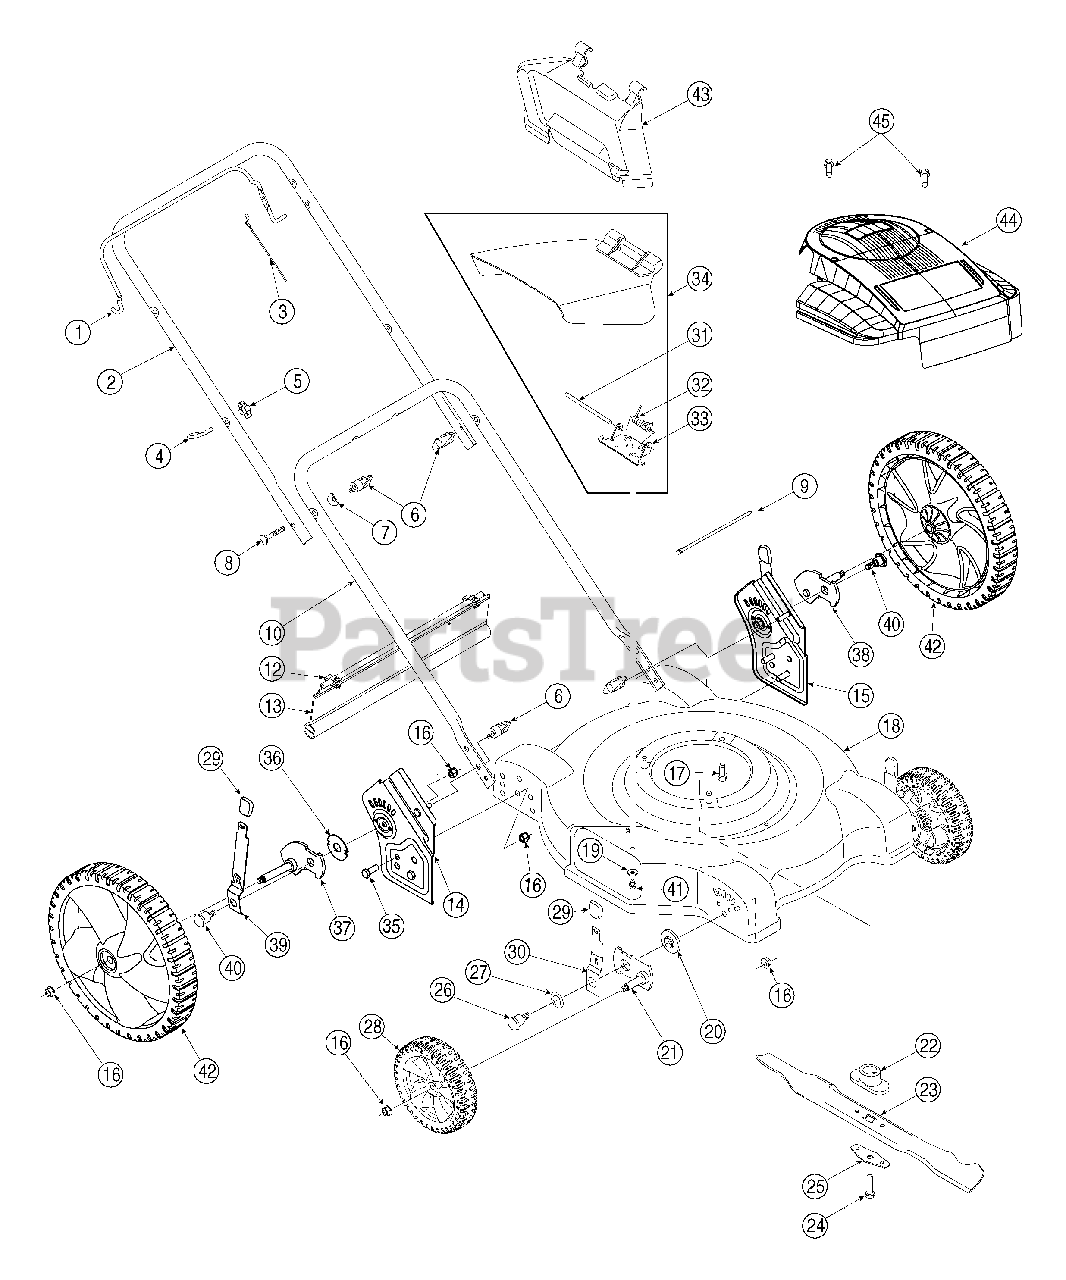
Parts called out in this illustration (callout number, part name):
3	Blade Control Cable - 37.25"
4	Eye Bolt
5	Wing Nut
6	Wing Nut
7	Shoulder Washer.320 ID x.93 OD
8	Carriage Bolt 5/16-18 x 2.0
9	Cable Tie
12	Hinge Clip
13	Trail Shield
17	Hex Washer Screw 3/8-16 x 1.0
19	Bell Washer.265 x.75
20	Height Adjuster Bearing
21	Pivot Arm Assembly
22	Blade Adapter
23	22" Mulching Blade
24	Hex Cap Screw 3/8-24 x 1.5
25	Blade Bell Support
26	Shoulder Screw 3/8 - 16 x.302
27	Bell Washer.760 ID x 1.25 OD
28	Front Wheel Assembly 7 x 1.8
29	Height Adjuster Knob
30	Front Spring Lever OD
31	Hinge Pin
32	Torsion Spring
33	Deflector Chute Adapter
34	Side Discharge Chute Assembly
35	Hex Cap Screw 3/8-16 x .75
36	Thrust Bearing.688 ID x 1.94 OD
37	Rear Pivot Arm Assembly - RH
38	Rear Pivot Arm Assembly - LH
39	Rear Spring Lever
40	Shoulder Screw 3/8 - 16 x.442
41	Screw 1/4-20 x.50
42	Rear Wheel Assembly 12 x 1.8
43	Mulching Baffle
44	Engine Shroud
45	Screw, #8-18 x 1.25
